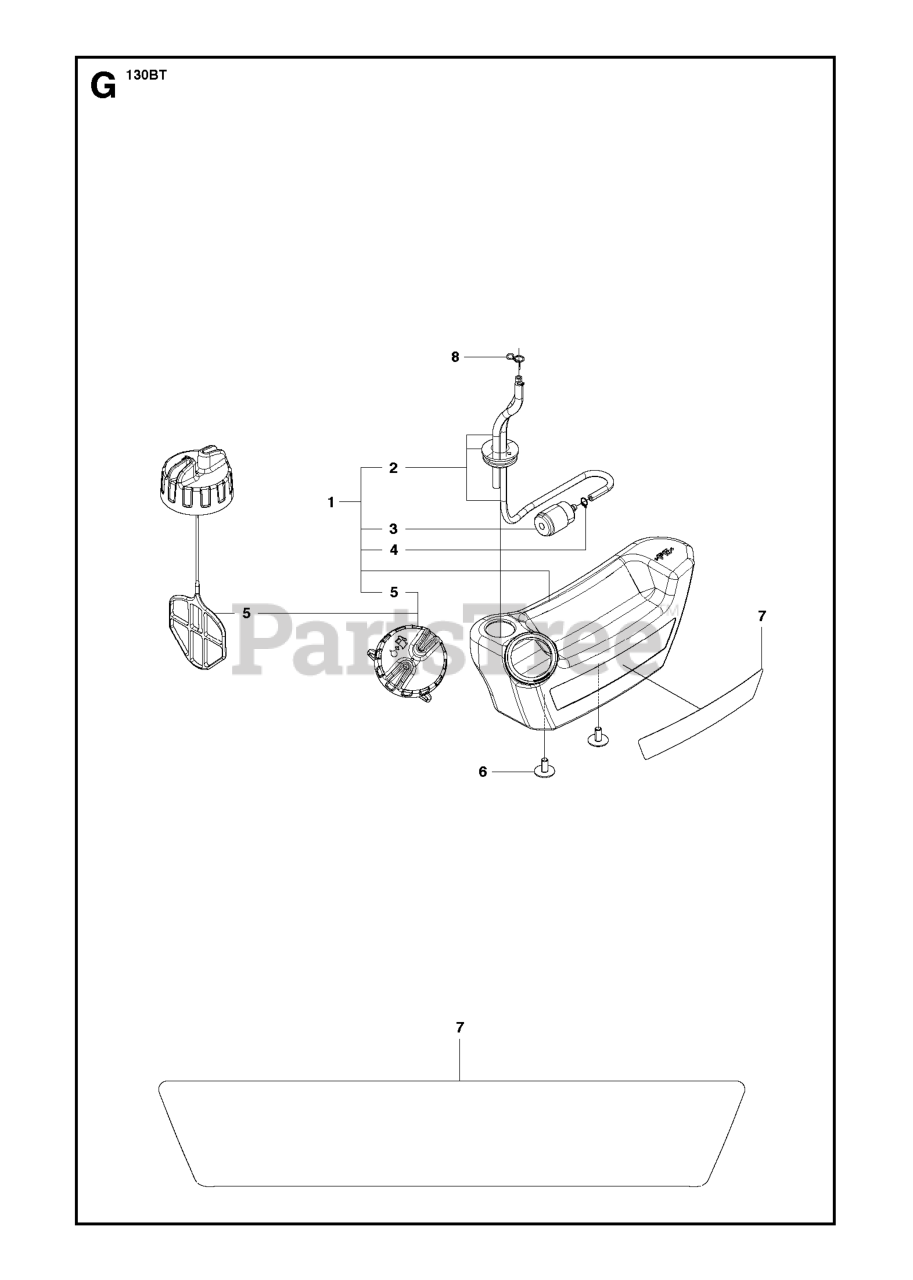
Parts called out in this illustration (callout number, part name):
1	FUEL TANK ASSY EVAP
2	PIPE C
3	RP FUEL FILTER
5	FUEL CAP ASSY
